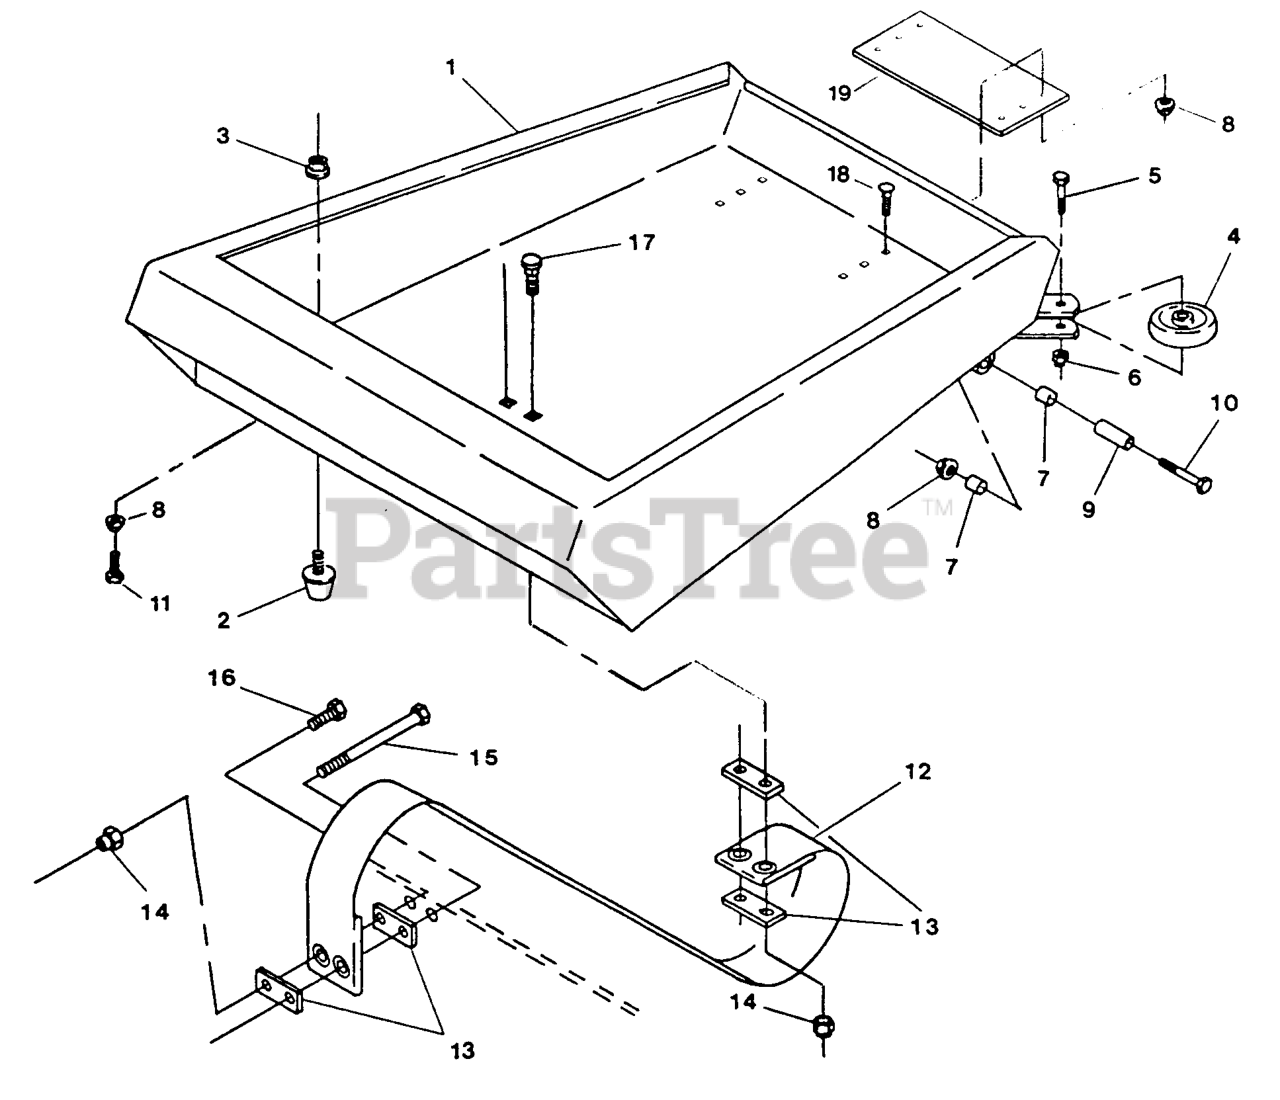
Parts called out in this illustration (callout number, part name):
2	BUMPER-RUBBER
4	WHEEL,RUBBER
7	SLEEVE-BEARING
9	BUSHING,BOX PIVOT
12	STRAP,BOX RESTRAINT
13	CLAMP,STRAP
17	Bolt, Carriage 1/4-20 X 1
19	WEIGHT,DUMP BOX PNTD
